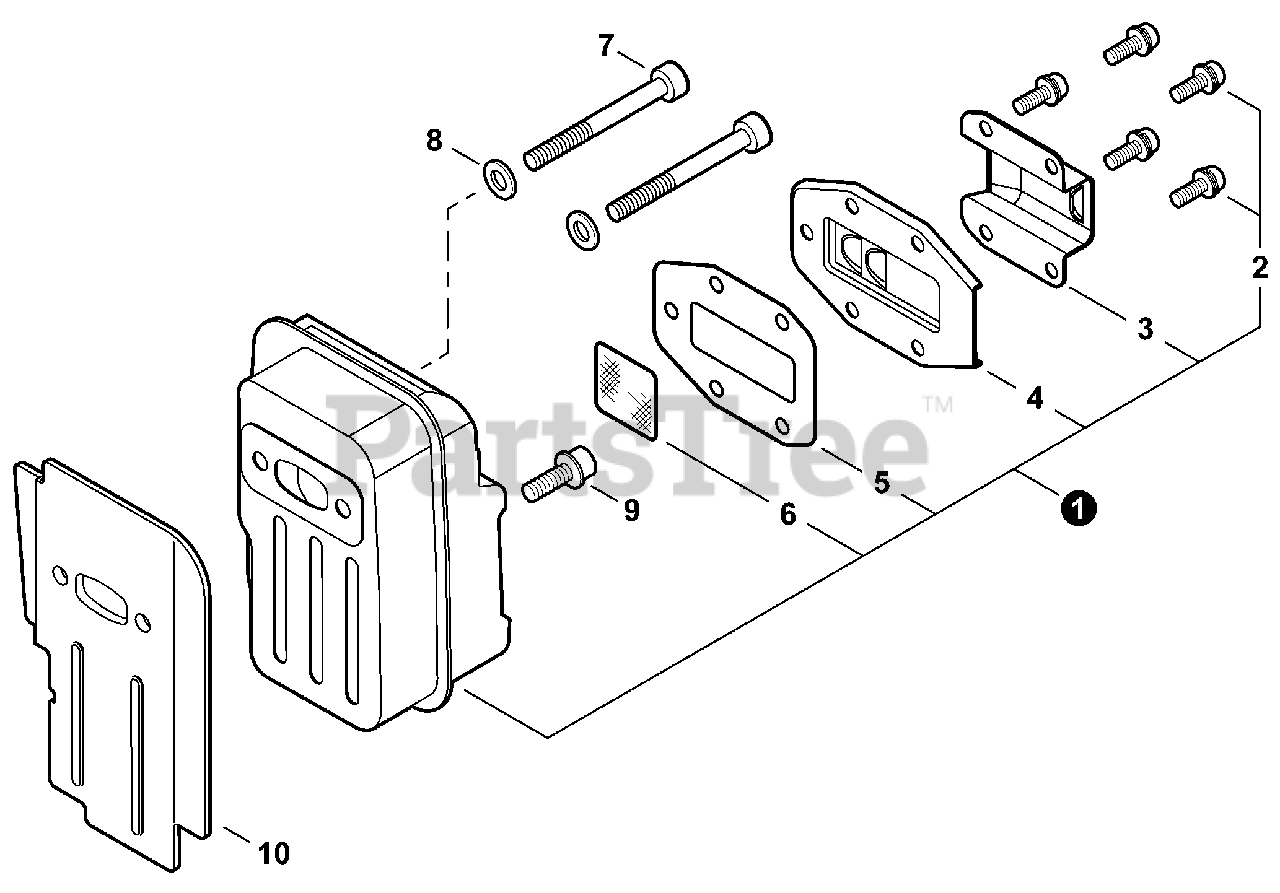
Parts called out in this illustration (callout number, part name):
1	MUFFLER ASSY
2	SCREW M4×8
3	OUTLET, EXHAUST
4	DEFLECTOR, EXHAUST
5	GASKET, EXHAUST
6	SCREEN, SPARK ARRESTER
7	BOLT M5×55
8	WASHER SS 5mm
9	BOLT 5×12
10	SHIELD, EXHAUST HEAT
